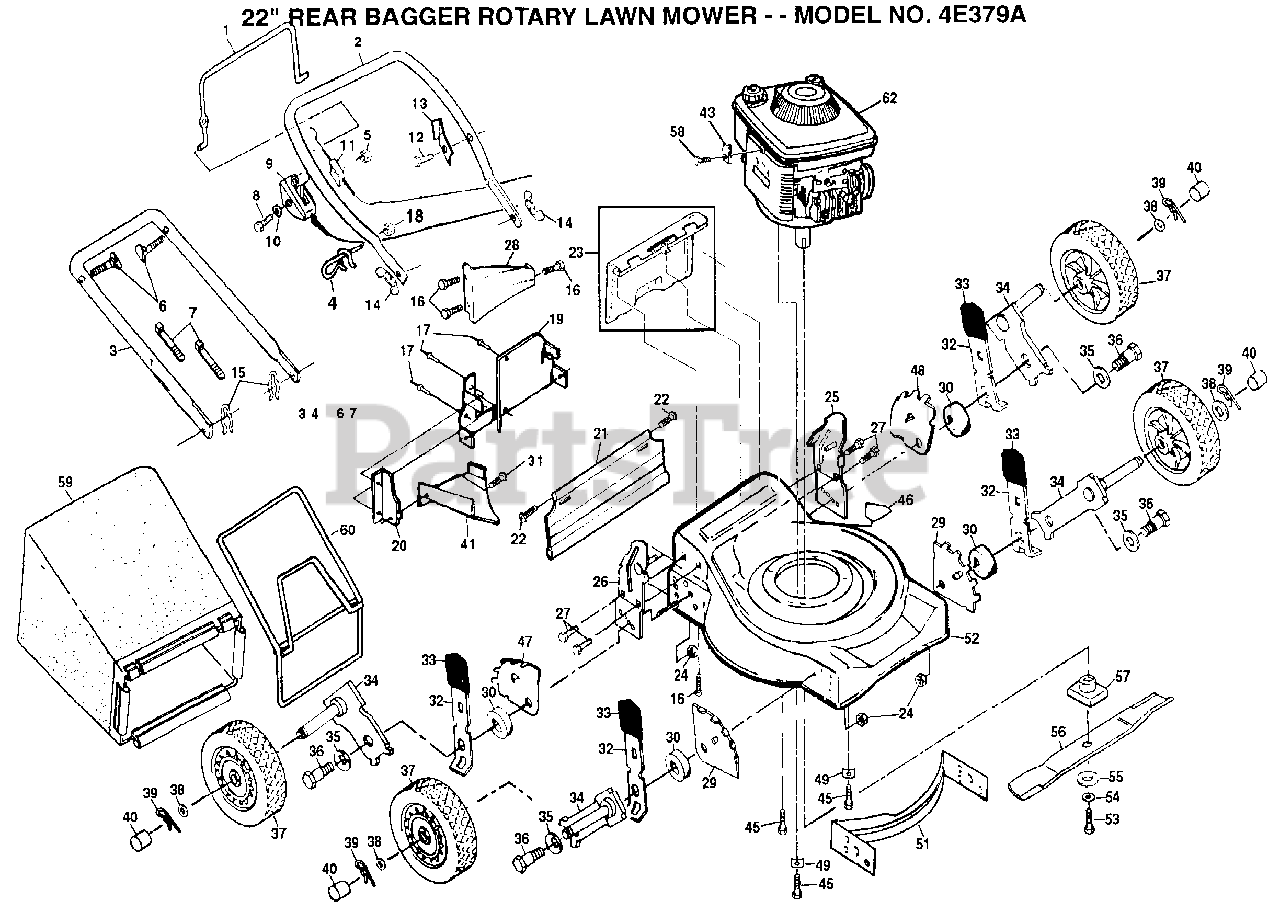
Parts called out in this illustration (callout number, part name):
1	CONTROL BAR
4	ROPE GUIDE
6	BOLT.HANDLE.LM
9	CNTL.THROT.47.5
10	WASHER PM
11	"CABLE,ENG ZONE CO"
12	TAPPING SCREW
13	"BRKT,UPSTOP"
14	"NUT,WING PM"
15	HAIRPIN COTTER
16	SCREW
17	BLIND RIVET
18	NUT
19	PLATE.BACK
22	HINGE SCREW
23	"KIT, REAR DOOR PM"
24	LOCKNUT PM
27	SCREW
28	REAR BAFFLE
31	SCREW PM
32	SPRING SELECTOR
33	KNOB PM
34	AXLE ARM
35	"WASHER, BELLEVIL."
38	WASHER
39	RETAINER CLIP PM
40	HUB CAP
41	DISCHARGE BAFFLE
43	CABLE CLAMP
45	SCREW
46	DECAL HYT
52	KIT.HSG.22RD.PUSH
53	SCREW
54	LOCKWASHER
55	"WASHER,HARDEN"
56	"BLADE.22"""
57	ADAPTOR.BLADE.LM
58	SCREW PM
59	GRASS BAG
60	CATCHER FRAME
